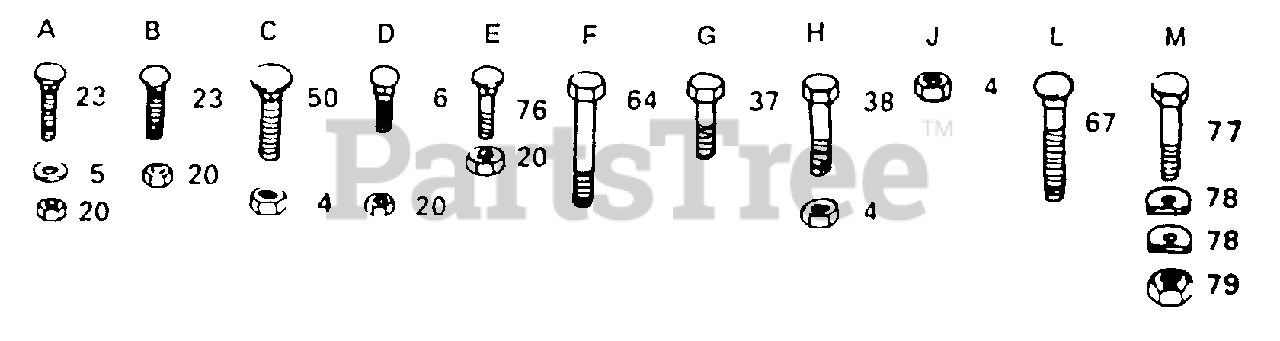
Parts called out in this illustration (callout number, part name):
4	Nut, Lock 3/8 - 16
5	Washer 11/32 x 3/4 x 16 Ga.
6	Bolt, Carr., 5/16-18 x 5/8
20	Nut, Lock 5/16 - 18
23	Bolt, Carriage 5/16-18 x 3/4
37	Screw, Hex Washer Hd. 3/8-16 x 7/8
38	Screw, Hex Washer Hd. 3/8-16 x 1-1/4
50	Bolt, Carriage 3/8-16 x 3/4
64	Bolt 3/8-16 x 5-1/2
67	Bolt, Carriage 3/8-16 x 1-1/4
76	Bolt, Carriage 5/16-18 x 3/4
77	Bolt Hex 1/4 x 20 x 3/4
78	Washer, Special
79	Nut, Lock 1/4-20
